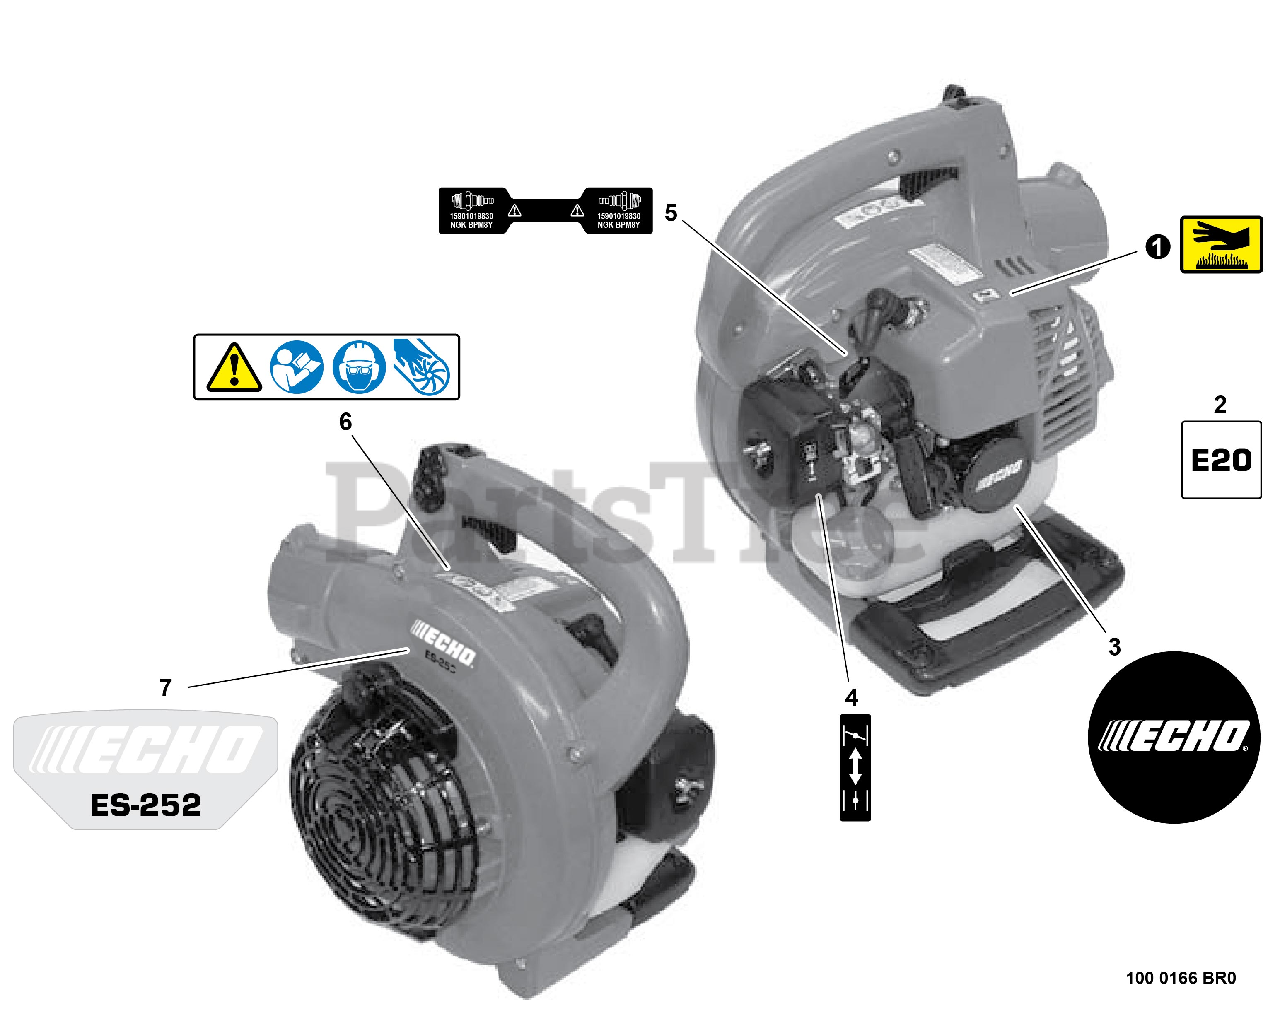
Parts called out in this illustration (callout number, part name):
1	LABEL - HOT SURFACE
2	LABEL - E20
3	LABEL - ECHO
4	LABEL - CHOKE
5	LABEL - SPARK PLUG -- BPM-8Y
6	LABEL - CAUTION
7	LABEL - MODEL ES-252
